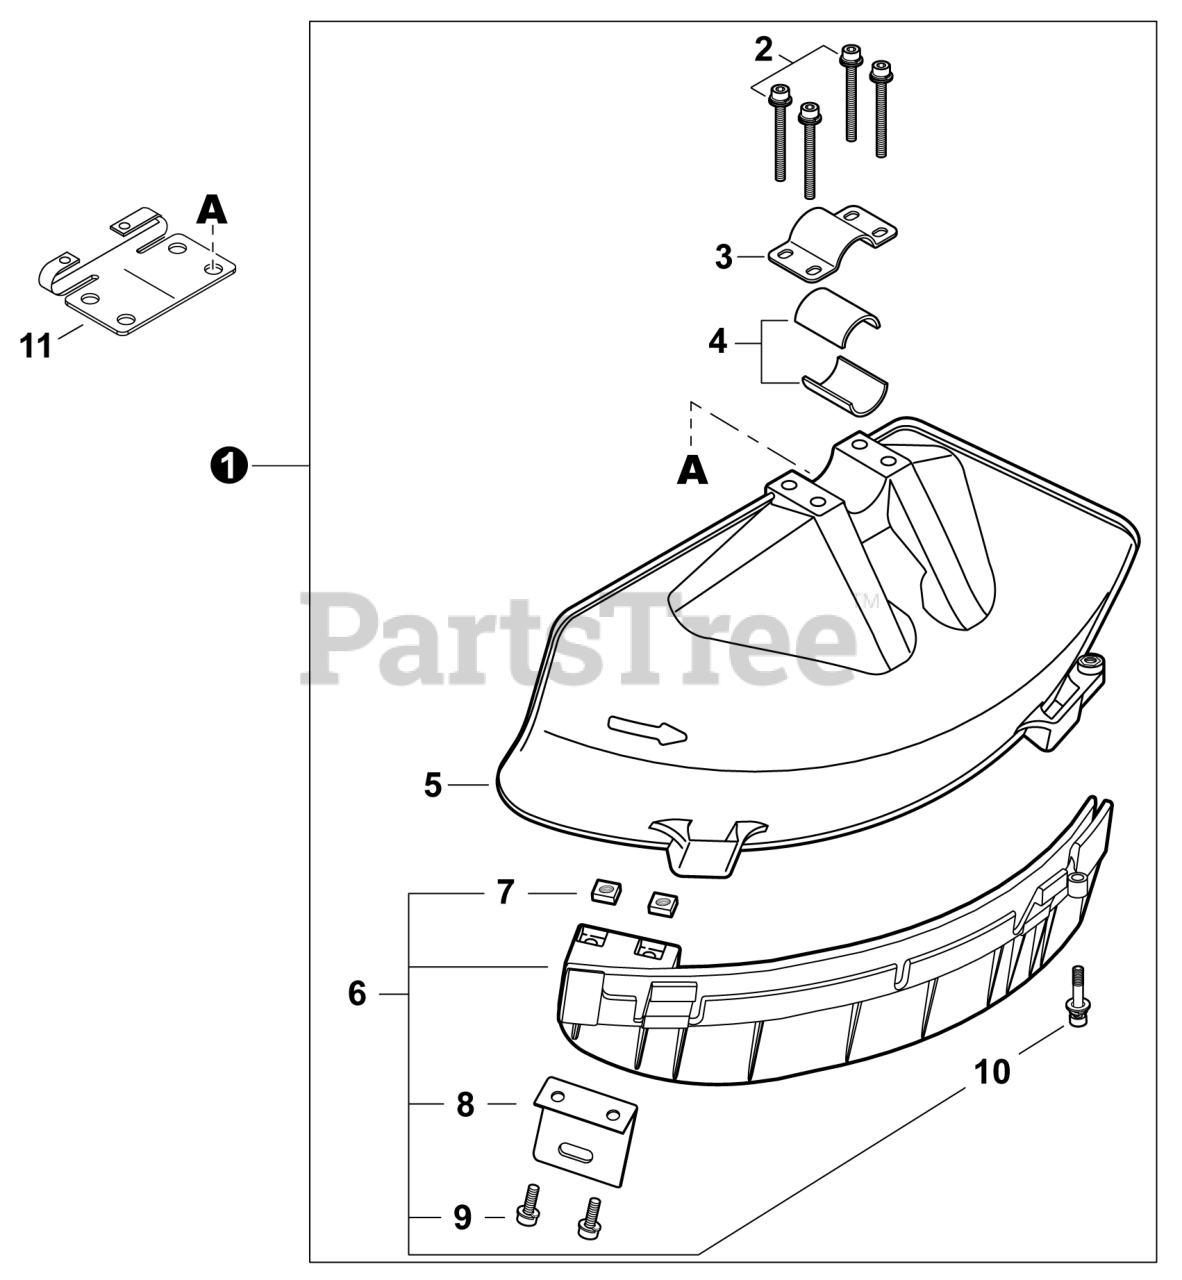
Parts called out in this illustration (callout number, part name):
1	SHIELD KIT, DEBRIS
2	BOLT M5x45
3	CLAMP, UPPER
5	SHIELD, DEBRIS - BLADE
6	EXTENSION ASSY, DEBRIS SHIELD
9	BOLT 5x16
10	BOLT M5x22
11	BRACKET, SHIELD
